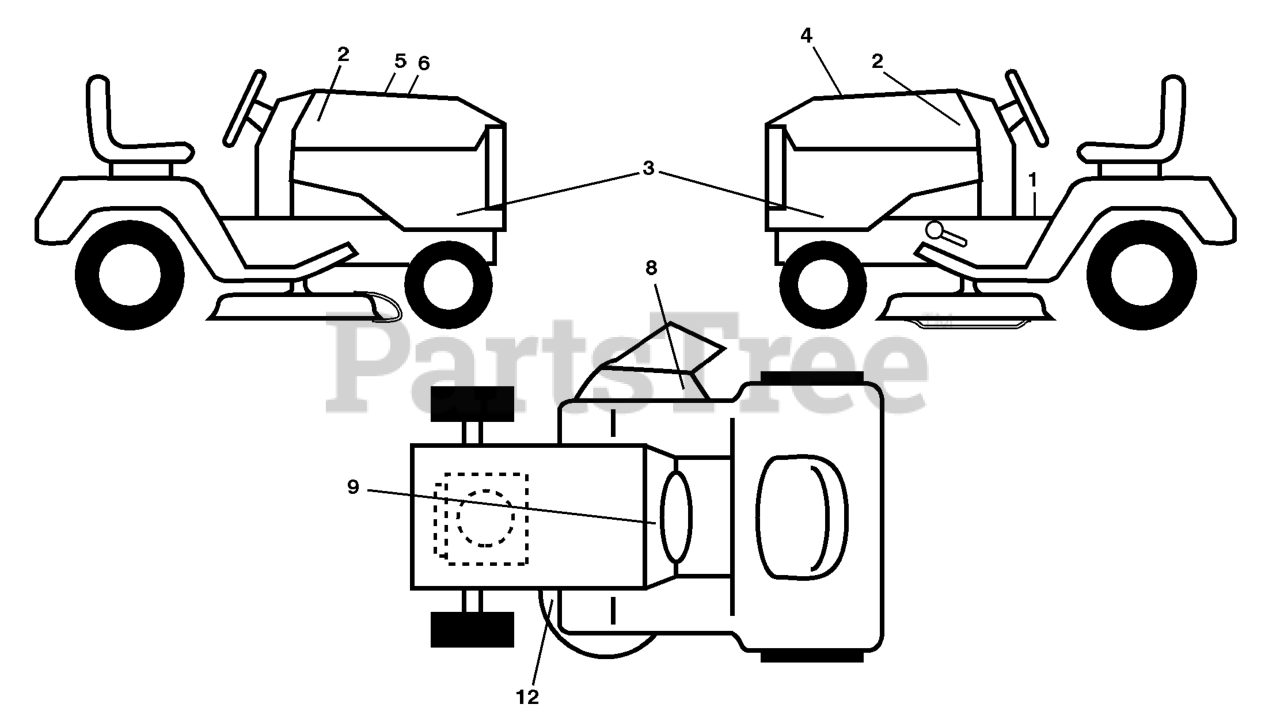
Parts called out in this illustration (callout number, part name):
1	DECAL.FENDER.WARNING.ENG
2	EMBLEM.HOOD.HUSQ.DEALER
3	DECAL.SDPNL.2348LS.ENDUR.HUSQ
4	DECAL.ENG.BSM44.23.ENDUR.27817
5	DECAL HOOD CUST. RESP.
6	DECAL.ENG.B&S.13.5HP..IC/OHV
8	DECAL.WARN.KEEP.HAND.AWAY
9	DECAL BTRY SYMBOLS
12	DECAL.MOWER.SCH.48/54
12	DECAL.DECK.AIR.INDUCTION.HUSQ
12	DECAL.BYPASS.FENDER.CRD.LT.YT
12	PAD, FOOTREST, LH
12	PAD, FOOTREST, RH
12	Manual, Owner's
